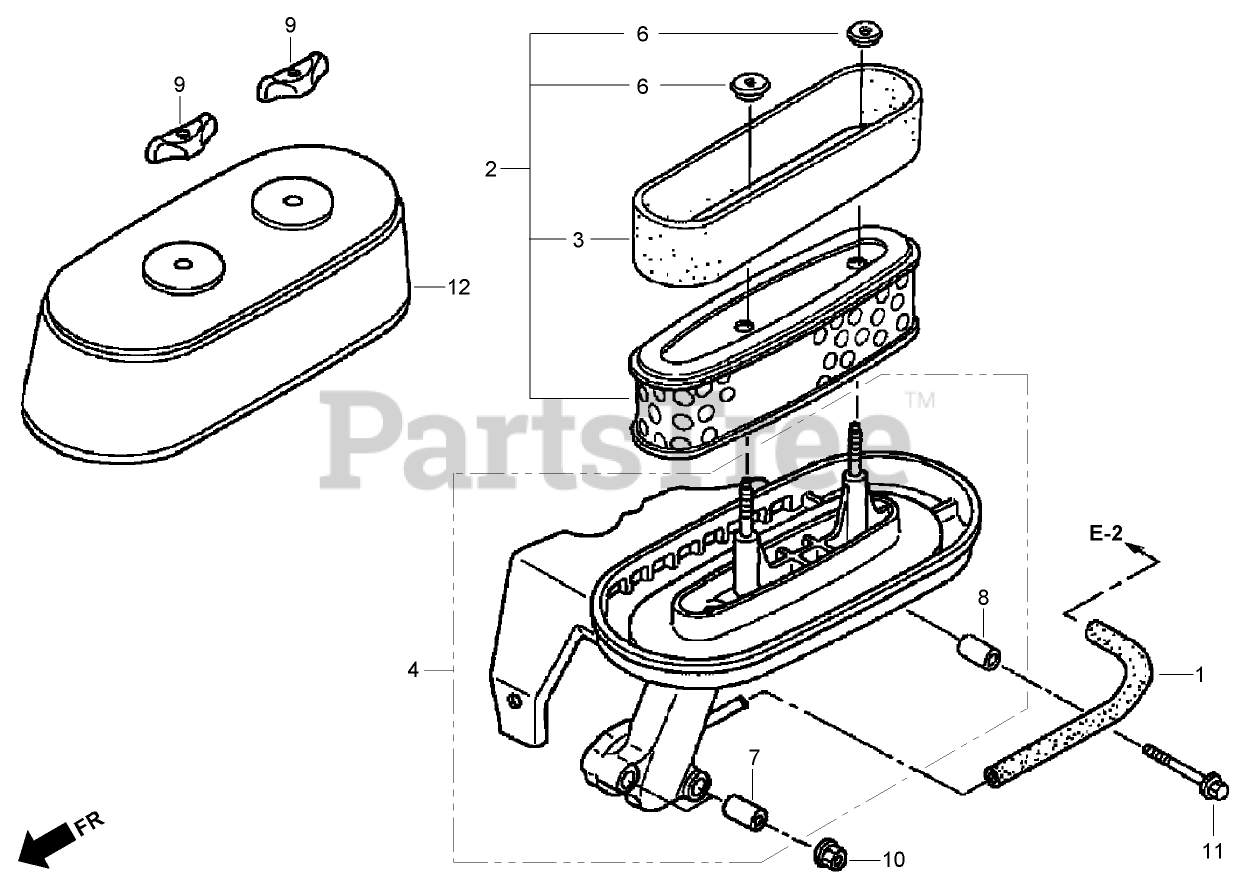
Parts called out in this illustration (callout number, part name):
1	Tube-Breather
2	ELEMENT-CLEANER, AIR
3	FILTER (OUTER)
4	HOUSING-CLEANER, AIR
6	GROMMET-CLEANER, AIR
7	COLLAR-CLEANER, AIR
8	COLLAR B-CLEANER, AIR
9	NUT-CLEANER, AIR
10	NUT-FLANGE (6 mm)
11	BOLT-FLANGE (6X35)
12	COVER-CLEANER, AIR (SERIAL NUMBERS UP TO 1036455)
12	COVER-CLEANER, AIR (Engine Serial No. From 1036456)
